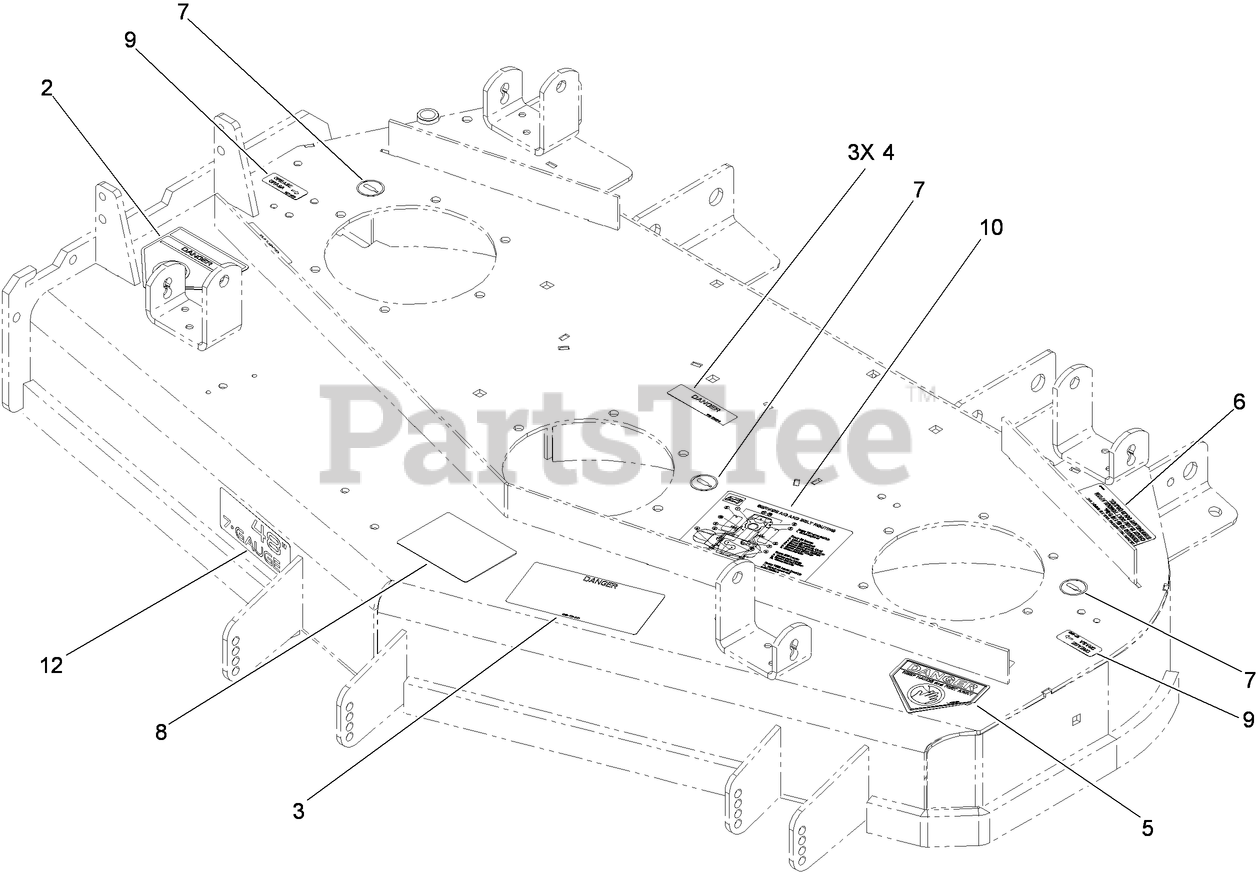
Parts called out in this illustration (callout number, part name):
2	DECAL-DANGER
3	DECAL-DANGER, THROWN OBJECT
4	DECAL-COVER, MISSING
5	DECAL-DANGER
6	DECAL-TORQUE
7	DECAL-GREASE
8	DECAL-SCALP, ANTI
9	Decal-Grease
10	DECAL-AID, SERVICE
